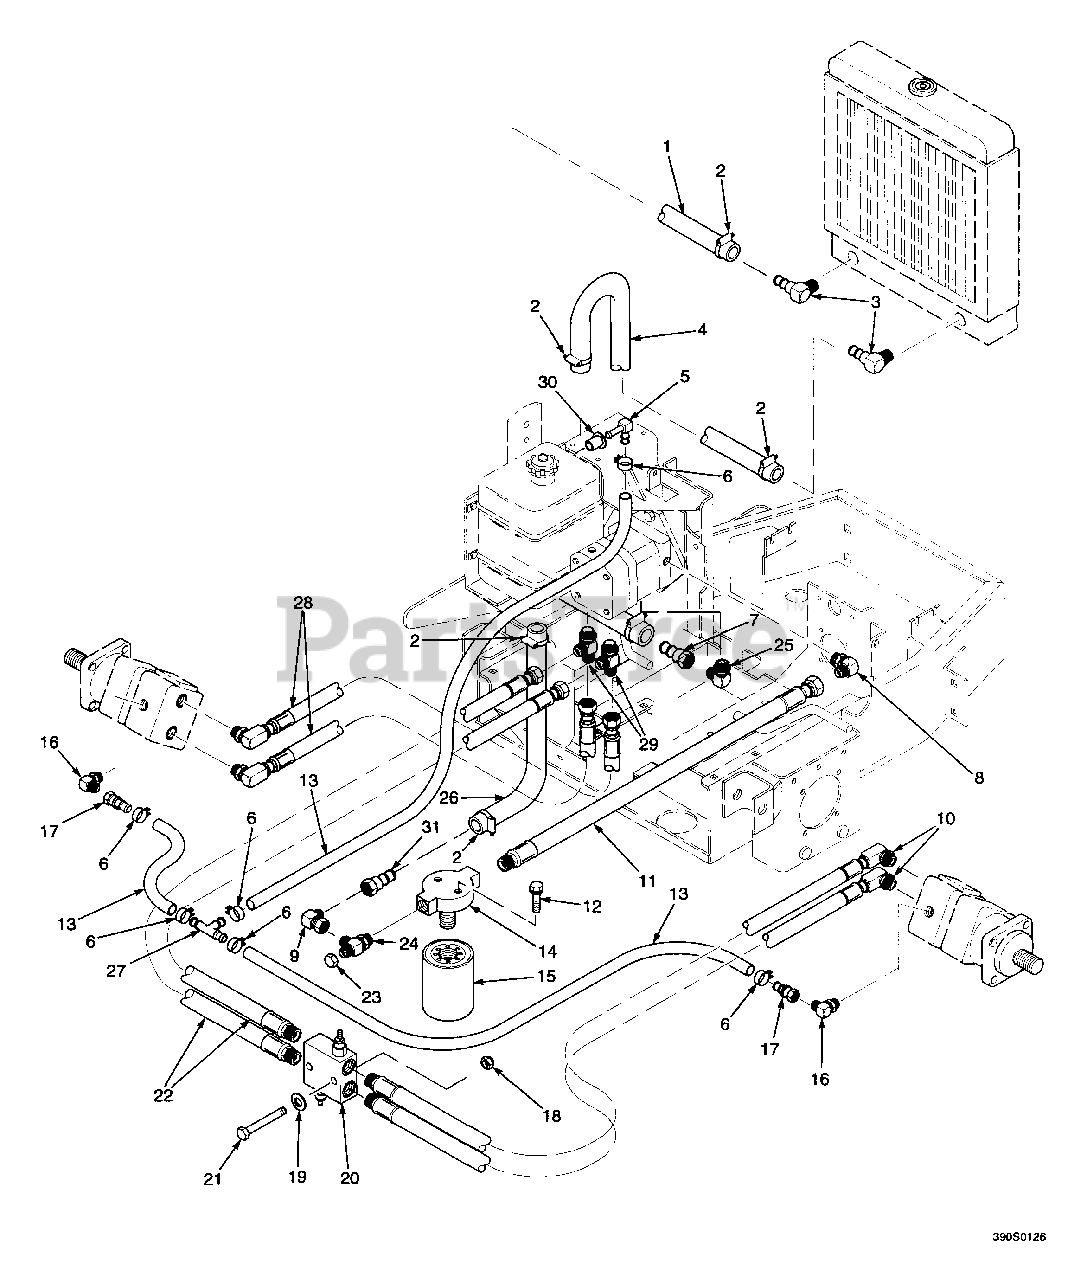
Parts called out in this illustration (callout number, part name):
1	Hose, 5/6 Hose Barb
2	Clamp, Hose
3	Elbow, 90ø,
4	Hose, 5/8 & 3/8 Hose Barb
5	Elbow, 90ø
6	Clamp, Hose
7	Coupling, Hose, 7/8-14 SAE x 5/8 Hose Barb
8	Elbow, 90ø, 1-1/16-12 JIC x 7/8-14 O-Ring
9	Elbow, 90ø, 3/4 JIC Swivel x 3/4 JIC
10	Hose Assembly, Left Motor
11	Hose Assembly, Pump Inlet
12	Serr. Fl. Hex Head Capscrew, 1/4-20 x 3/4
13	Hose, Hydraulic, 1/4"
14	Filter Head
15	Filter, Hydraulic
16	Elbow, 90ø
17	Coupling, Hose
18	Hex Nut, Elastic Stop, 5/16-18
19	Flatwasher, 5/16 (.344 x .688 x .065)
20	Relief Valve, Dual Cross-Over
21	Bolt, Hex Head, 5/16-18 x 2-1/4
22	Hose Assembly, Pump to Valve
23	Tube Cap, 1-1/16-12
24	Tee, Run, 3/4 x 3/4
25	Elbow, 90ø, 7/8-14 JIC x 7/8-14 O-ring
26	Hose, 3/4
27	Tee, Pushlock, 1/2
28	Hose Assembly, Right Motor
29	Tee, Run
30	Bushing
31	Hose Barb to JIC Swivel
